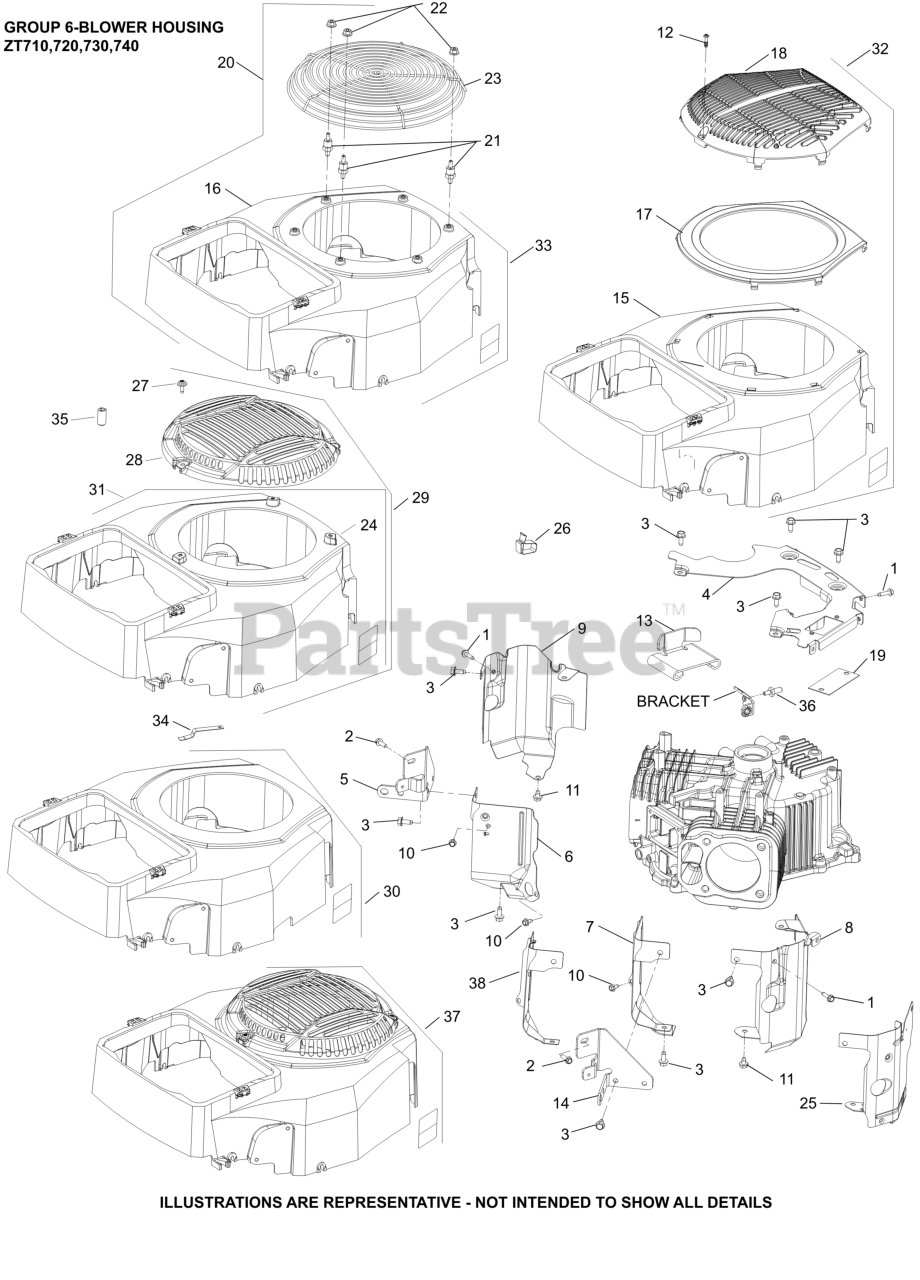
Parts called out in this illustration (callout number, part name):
1	SCREW, THD FRM-USE 25 086 473-S
2	SCREW, HI-LOW
3	SCREW, THREAD FORMING
4	PLATE, BACKING
5	BRACKET, AIR CLEANER BASE (#1 SIDE)
6	BAFFLE, VALLEY #1
7	BAFFLE, VALLEY #2
8	BAFFLE, LEFT BARREL
9	BAFFLE, RIGHT BARREL
10	SCREW, THREAD FORMING
12	SCREW, M5-2.42 (PT) THREAD
14	BRACKET, AIR CLEANER BASE (#2 SIDE)
18	GUARD, FIXED
32	KIT, BLOWER HOUSING
NI	REG/RECT (15AMP,HW,OVP)
NI	PLATE ASSEMBLY, BACKING (15A)
